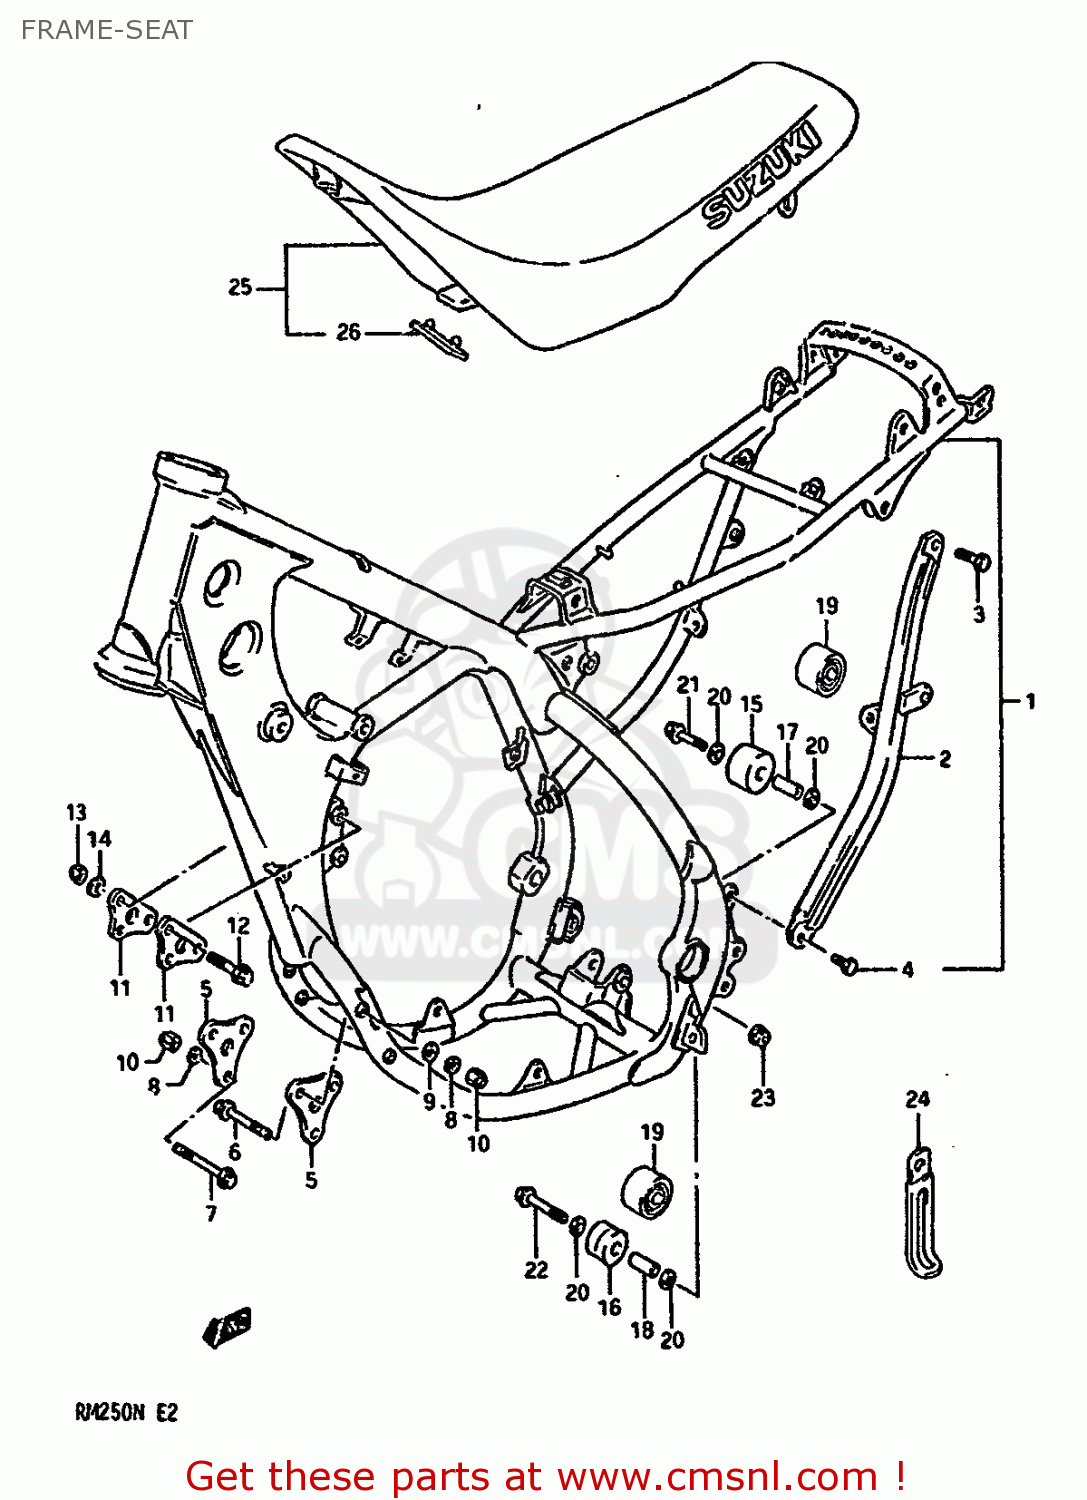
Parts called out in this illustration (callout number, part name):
1	FRAME SET
2	TUBE,FRAME SIDE,LEFT
3	BOLT
4	BOLT
5	PLATE,ENG MTG FR
6	BOLT
7	BOLT(8X60)
8	LOCK WASHER
9	WASHER
10	NUT
11	PLATE,ENGINE MOUNTING
12	BOLT
13	NUT
14	WASHER
15	ROLLER,CHAIN CONTROL
16	ROLLER,CHAIN CONTROL
17	SPACER (8.6X13.8X28)
18	SPACER(8.6X12X25.5)
19	ROLLER,CHAIN
20	WASHER
21	BOLT(8X41)
22	BOLT(8X45)
23	NUT
24	CLAMP
25	SEAT SET
26	CUSHION
